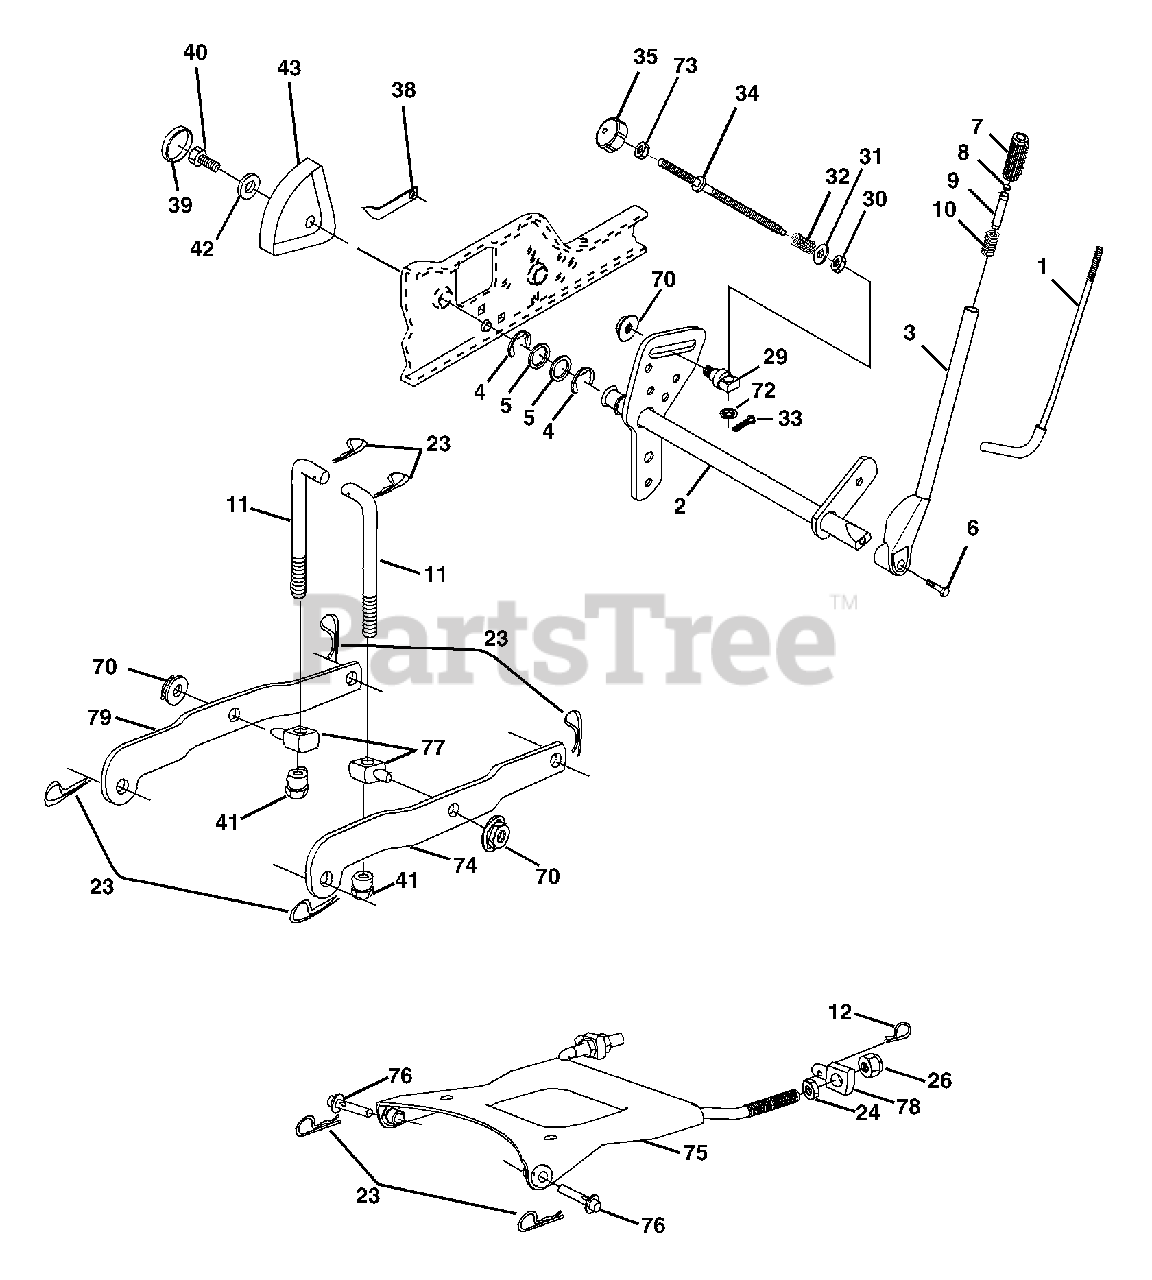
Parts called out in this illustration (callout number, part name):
1	Rod Asm., Lever
2	Shaft Asm., Lift Vgt
3	Lever Asm., Lift Rh
4	E-Ring Truarc #5133-87
5	Washer 29/32 x 1-1/4 x 16 Ga.
6	Bolt, Fin Hex 3/8-16 x 1-1/2
7	Grip, Handle
8	Button Plunger
9	Plunger, Lever Lift
11	Link Lift
12	Retainer, Spring
23	Retainer, Spring
24	Nut, Jam Hex 1/2-13 unc
26	Nut Crownlock 1/2-13 unc
29	Trunnion Infin Height
30	Nut, Special
31	Washer 13/32 x 5/8 x 16 Ga.
32	Spring, Compression Inf Hgt
33	Pin, Cotter 3/32 x 1/2
34	Rod, Adj Lift
35	Knob, Inf 3/8-16 Unc
38	Pointer Height Indicator
39	Plug, Hole Blk. 1.485/1.515 Dia.
40	Screw 5/16-18 x 1
41	Nut, Lift Link
42	Washer 11/32 x 1-1/2 x 10 Ga.
43	Scale, Indicator Height
70	Nut Hex Flange Lock
72	Nut Push Phos & Oil
73	Nut, Hex Jam 3/8-16 unc
74	Arm, Suspension Rear RH
75	Plate, Asm, Susp, Front
76	Pin Flange
77	Trunnion Susp. Arm
78	Trunnion, Front, Susp
79	Arm, Suspension Rear LH
